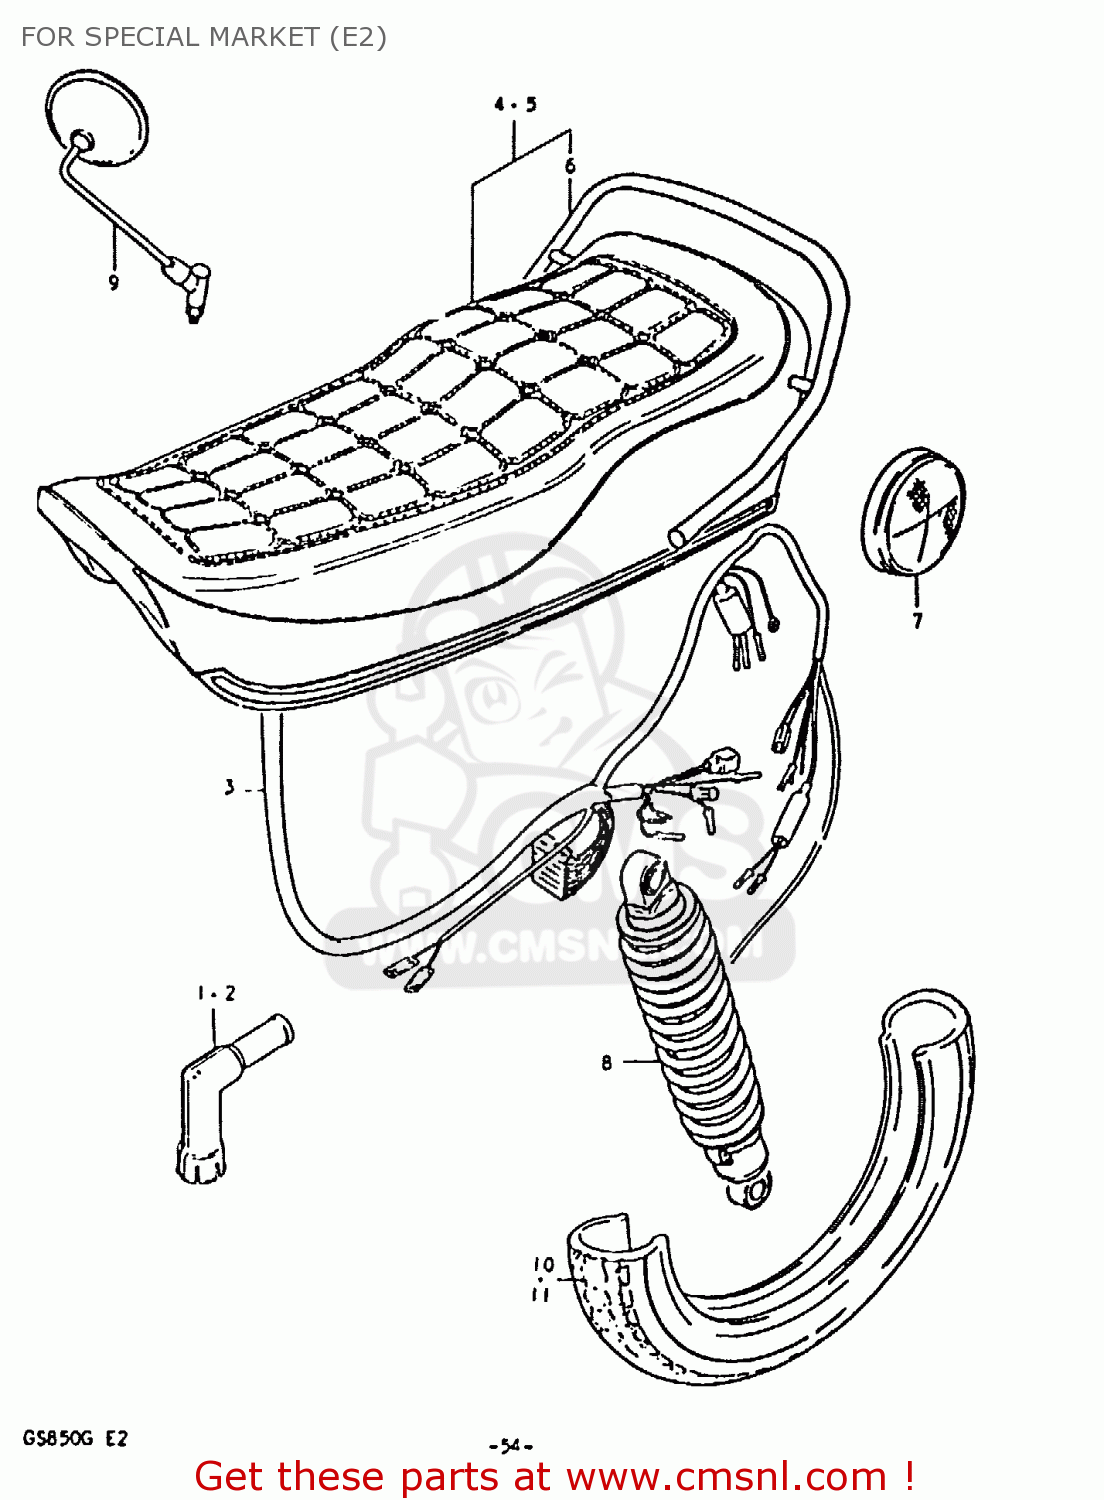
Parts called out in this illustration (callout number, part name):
1	CAP,SPARK PLUG
2	CAP, SPARK PLUG (S)
3	HARNESS,WIRING
4	SEAT ASSY (FLAT TYPE)
5	SEAT ASSY
6	HANDLE, PILLION RIDER
7	REFLEX REFLECTOR,RR
8	SHOCK ABSORBER, REAR
9	MIRROR ASSY,RH
10	TIRE,FRONT
11	TIRE
